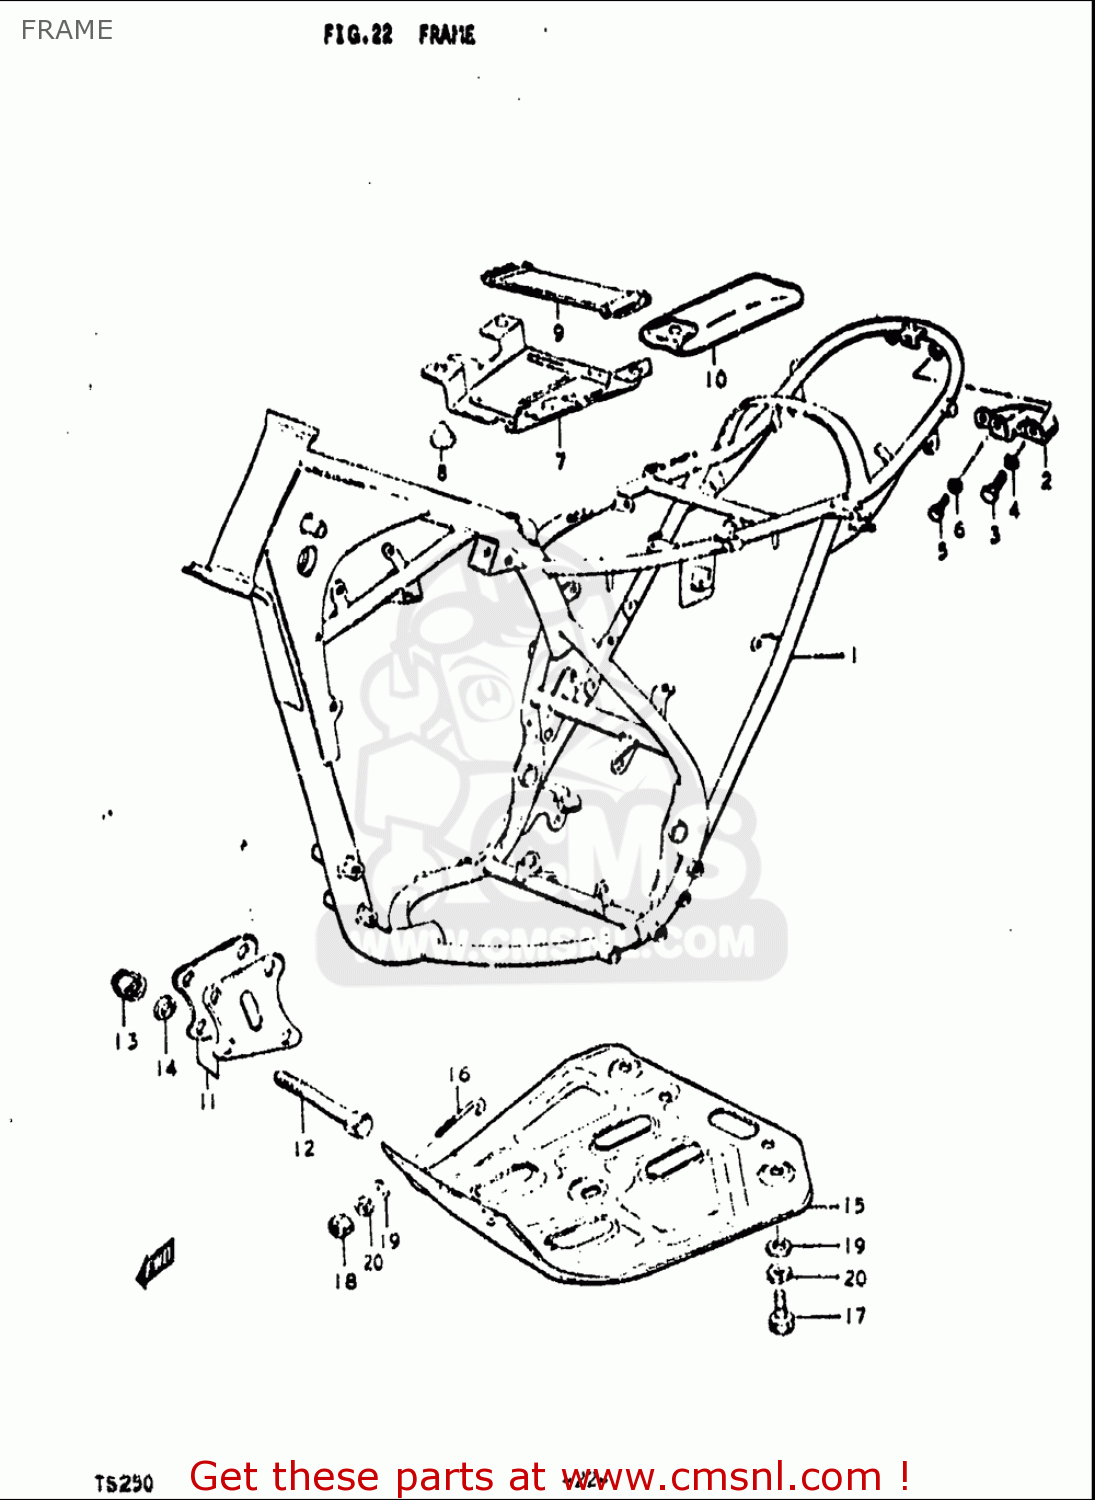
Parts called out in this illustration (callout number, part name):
3	BOLT
4	WASHER,LOCK
5	BOLT
6	WASHER,LOCK
8	CUSHION
9	BAND
10	TOOL ASSY
12	BOLT
13	NUT
14	WASHER
17	BOLT
18	NUT
19	WASHER
20	WASHER,LOCK
